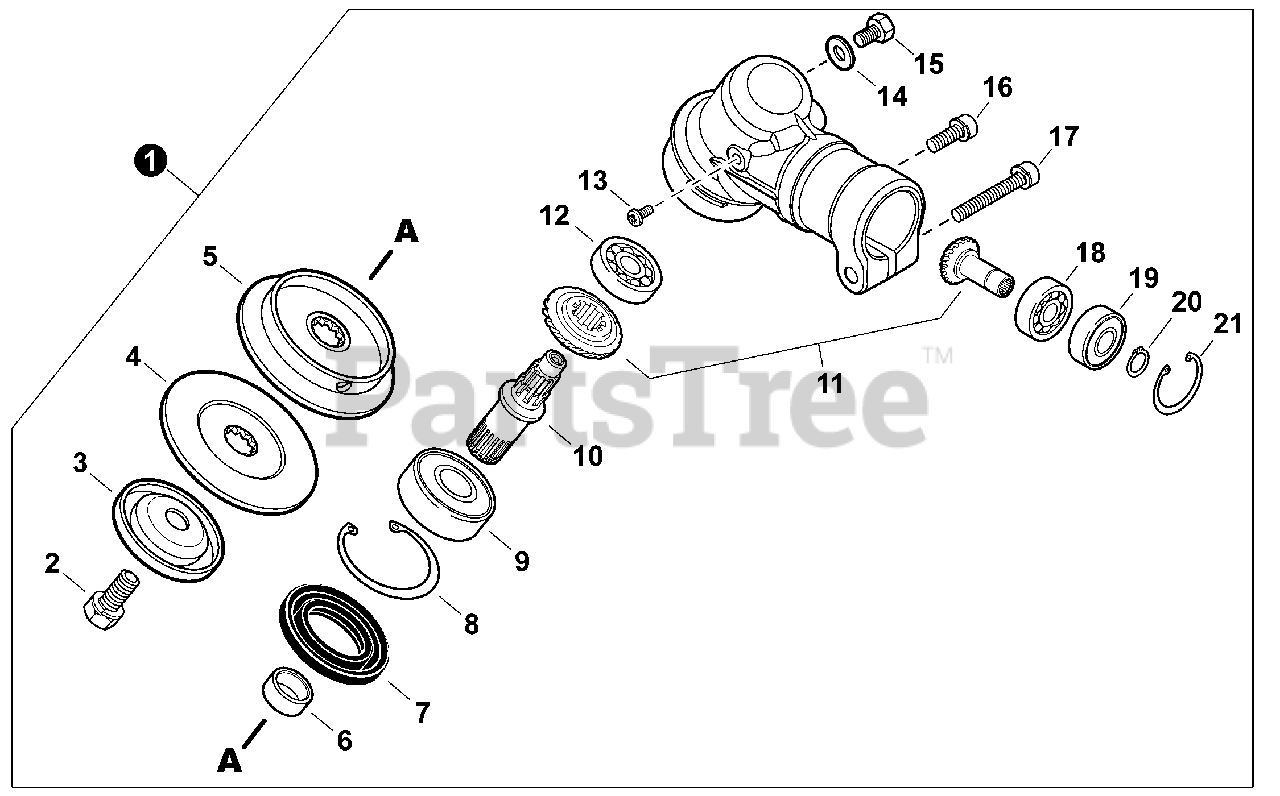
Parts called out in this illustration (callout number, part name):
1	GEAR CASE ASSY
3	GUARD, BOLT
4	PLATE, ADAPTOR - LOWER
5	PLATE, ADAPTOR - UPPER
7	SEAL, OIL
8	RING, SNAP Ø32
9	BEARING, BALL 6201
10	SHAFT, GEAR
11	GEAR SET
12	BEARING, BALL 609
13	SCREW M4×6
14	WASHER 6.5×11.5×0.8
15	BOLT M6×10
16	BOLT M5×10
17	BOLT M6×40
18	BEARING, BALL 6000
19	BEARING, BALL 6000ZZ
20	RING, SNAP Ø10
21	RING, SNAP Ø26
